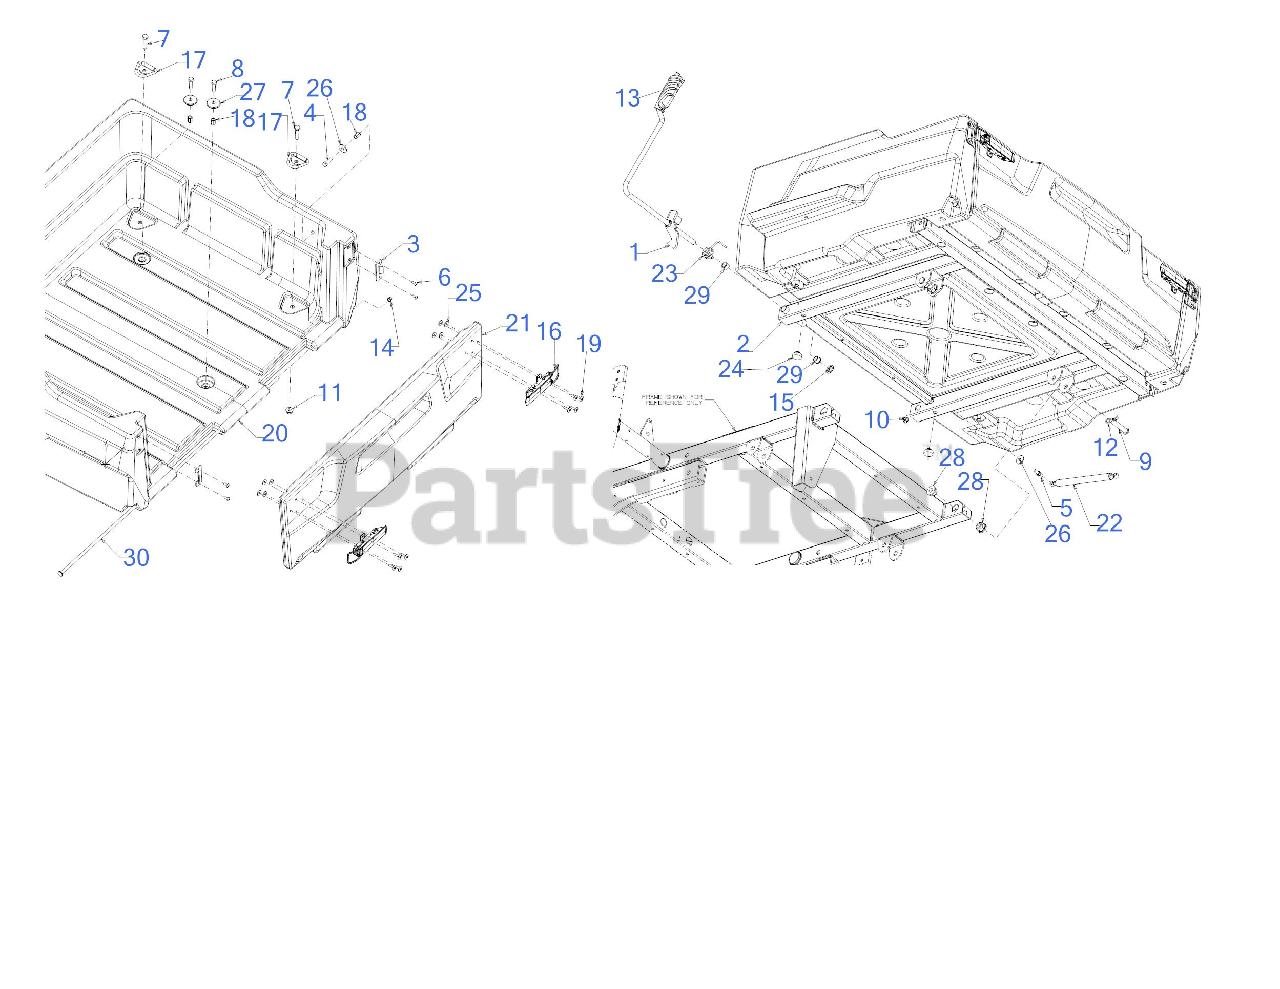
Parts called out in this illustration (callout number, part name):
4	SCREW 5/16-18 x 1.0 GR5
5	BALL STUD 5/16-18
6	SCREW #10-24 x .500
7	SCREW 3/8-16 x 1.50
8	SCREW 5/16-18 x 1.25 GR5
9	CLEVIS PIN .494 x 2.528
10	FLANGE LOCK NUT 5/16-18
12	BOW TIE COTTER PIN
16	OVER CENTER DRAW LATCH
17	TIE DOWN MOUNT
18	NUT RIVET 5/16-18
19	POP RIVET - .188 DIAMETER
22	GAS 7.87 STROKE SPRING
23	TORSION SPRING
24	RUBBER BUMPER 1.000 x .313
25	FLAT WASHER .194x.620x.063
26	FLAT WASHER 1.0 OD:.331 ID
27	SHOULDER SPACER
28	FLANGE BEARING
29	FLANGE BUSHING
30	TAIL GATE ROD
